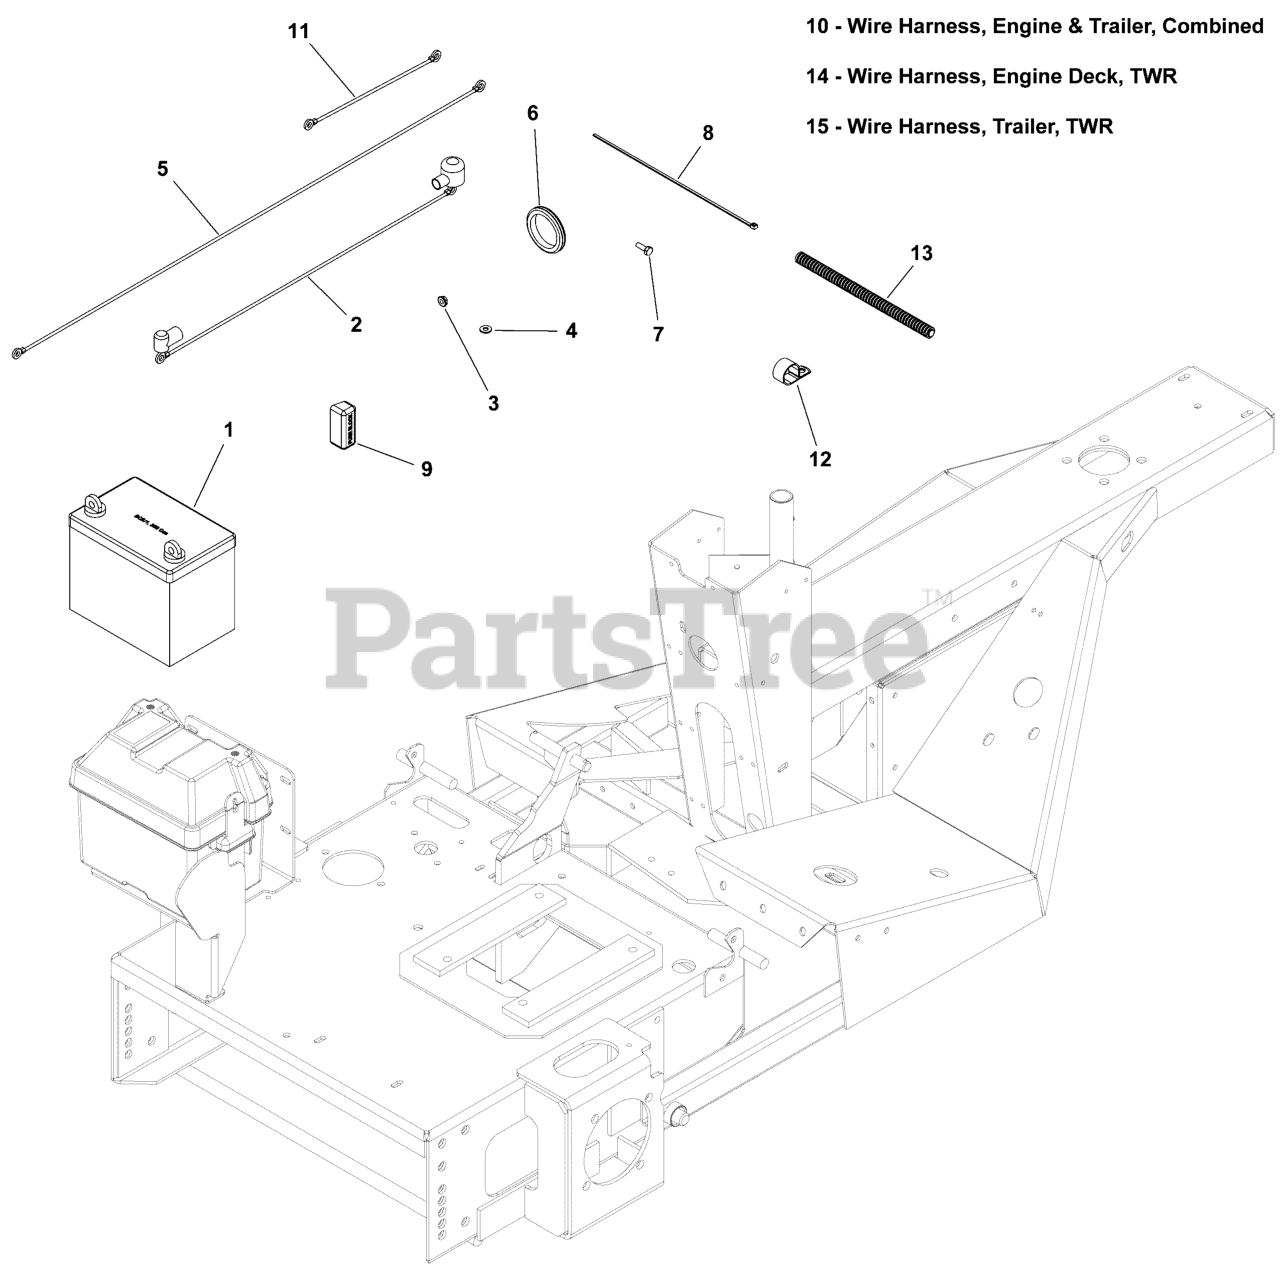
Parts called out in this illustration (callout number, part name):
1	BATTERY, 11U1L, 350 CCA
2	BATTERY CABLE, POS, 22, 1/4-5/16
3	NUT, 1/4-20 HEX SERR. FLANGE
4	WASHER, 1/4 SAE
5	BATTERY CABLE, NEG, 35, 1/4-5/16
6	GROMMET, 2" ID
7	BOLT, 1/4"-20 X 3/4" GD5 YZ
8	TIE, SELF-LOCKING, 12"
9	COVER, VINYL, FUSE BLOCK
10	WIRE HARNESS 3-WHEEL RIDER
11	BATTERY CABLE, NEGATIVE, 10
12	CLAMP, VINYL INSULATED, 1.00
13	WIRE LOOM, 3/8 ID X 10 IN
14	WIRE HARNESS ENGINE DECK TWR
15	WIRE HARNESS TRAILER TWR
